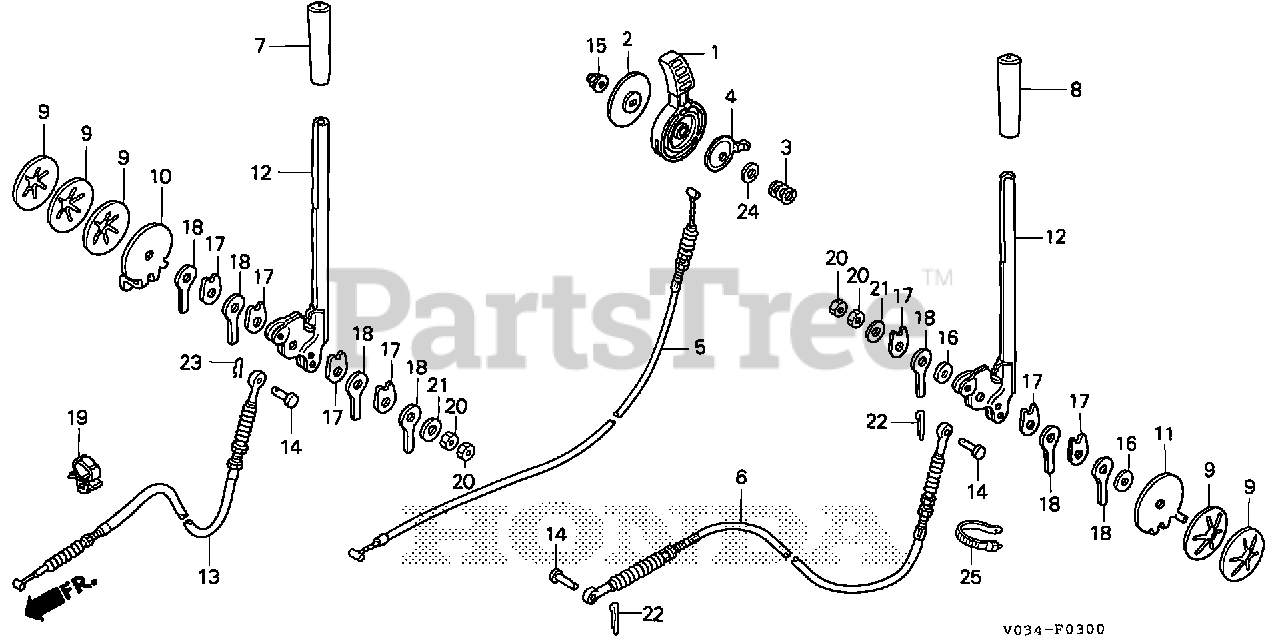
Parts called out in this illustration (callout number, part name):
1	LEVER, THROTTLE
2	PLATE, THROTTLE LEVER
3	SPRING, THROTTLE LEVER
4	SEAT, SPRING
5	CABLE, THROTTLE
6	CABLE, CHANGE
7	GRIP, CHANGE LEVER
8	GRIP, CHANGE LEVER
9	SPRING, ADJUSTING ARM
10	PLATE, R. STOPPER
11	PLATE, L. STOPPER
12	LEVER, CHANGE
13	CABLE, CHUTE GUIDE
14	PIN, CONTROL BOX SETTING
15	NUT, SELF-LOCK (6MM)
16	WASHER, LOCK
17	WASHER, FRICTION
18	WASHER, FRICTION SETTING
19	CLAMP, CABLE
20	NUT, HEX. (8MM)
21	WASHER, PLAIN (8MM)
22	PIN, SPLIT (2.0X12)
23	PIN, LOCK (6MM)
24	WASHER (10.2MM)
24	WASHER, PLAIN (10MM)
25	BAND, SUCTION HOSE (BLACK)
